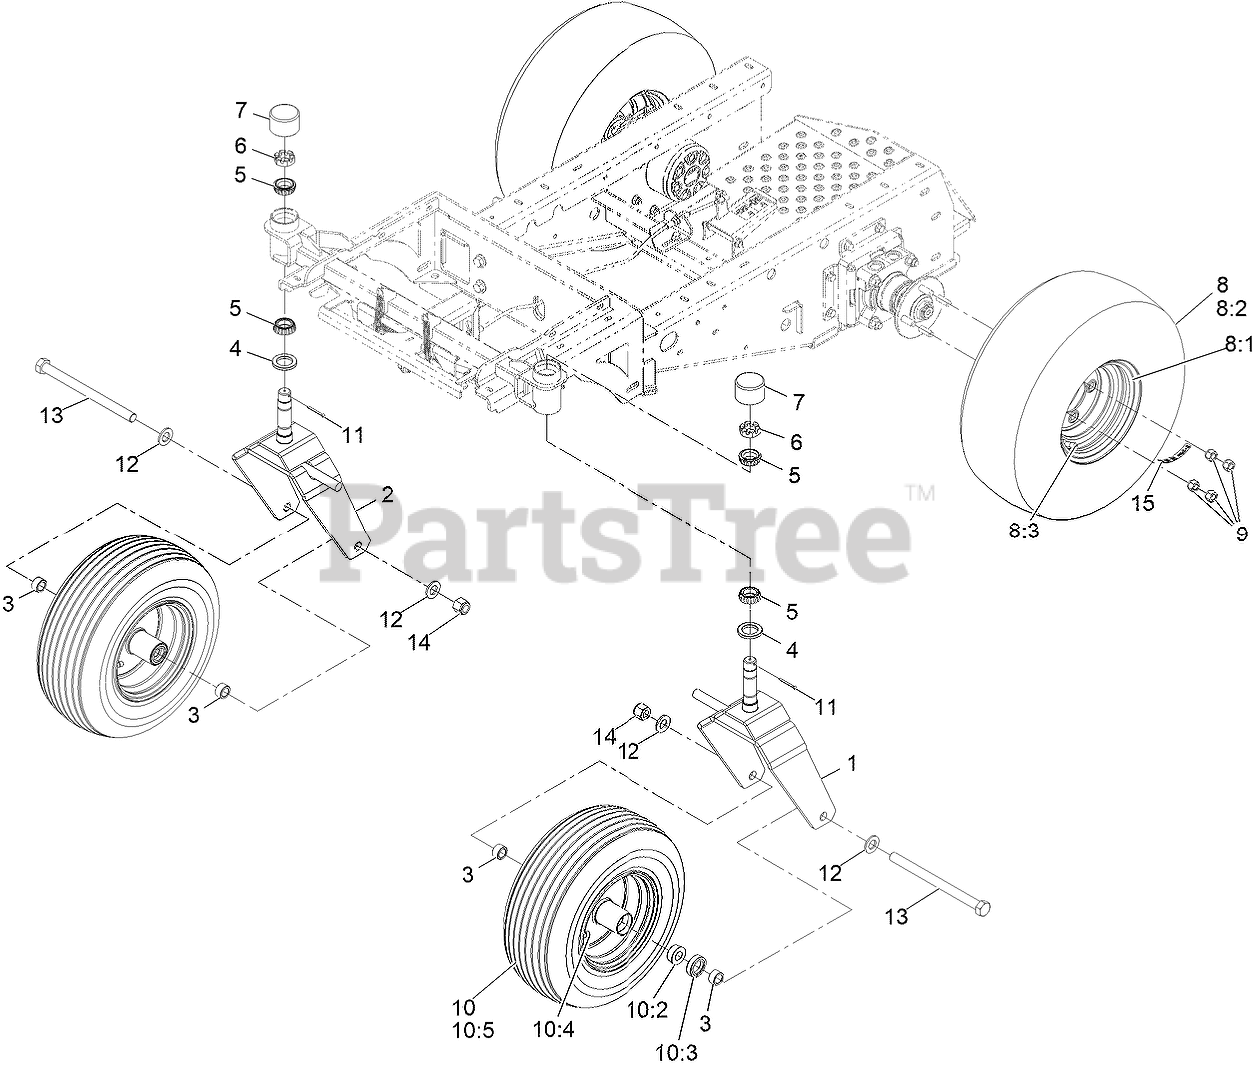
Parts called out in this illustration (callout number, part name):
1	X-REF TO 135-5441-03
2	X-REF TO 135-5446-03
3	SPACER-AXLE
4	SEAL-GREASE
5	CONE-BEARING, OUTER
6	NUT-SHH
7	CAP-DUST, RUBBER
8	WHEEL AND TIRE ASM
8:1	Tire- 20 X 8 4 Ply
8:2	Rim-8X5.375, Centered
8:3	Stem-Valve
9	NUT-LUG
10	WHEEL AND TIRE ASM
10:2	TIRE-RIB
10:3	BEARING-CONE, TAPERED ROLLER
10:4	VALVE
10:5	SEAL-CASTER
11	Pin-Cotter
12	WASHER-FLAT
13	SCREW-HH
14	NUT-LOCK, NI
15	DECAL-TORQUE, WHEEL HUB LUG
